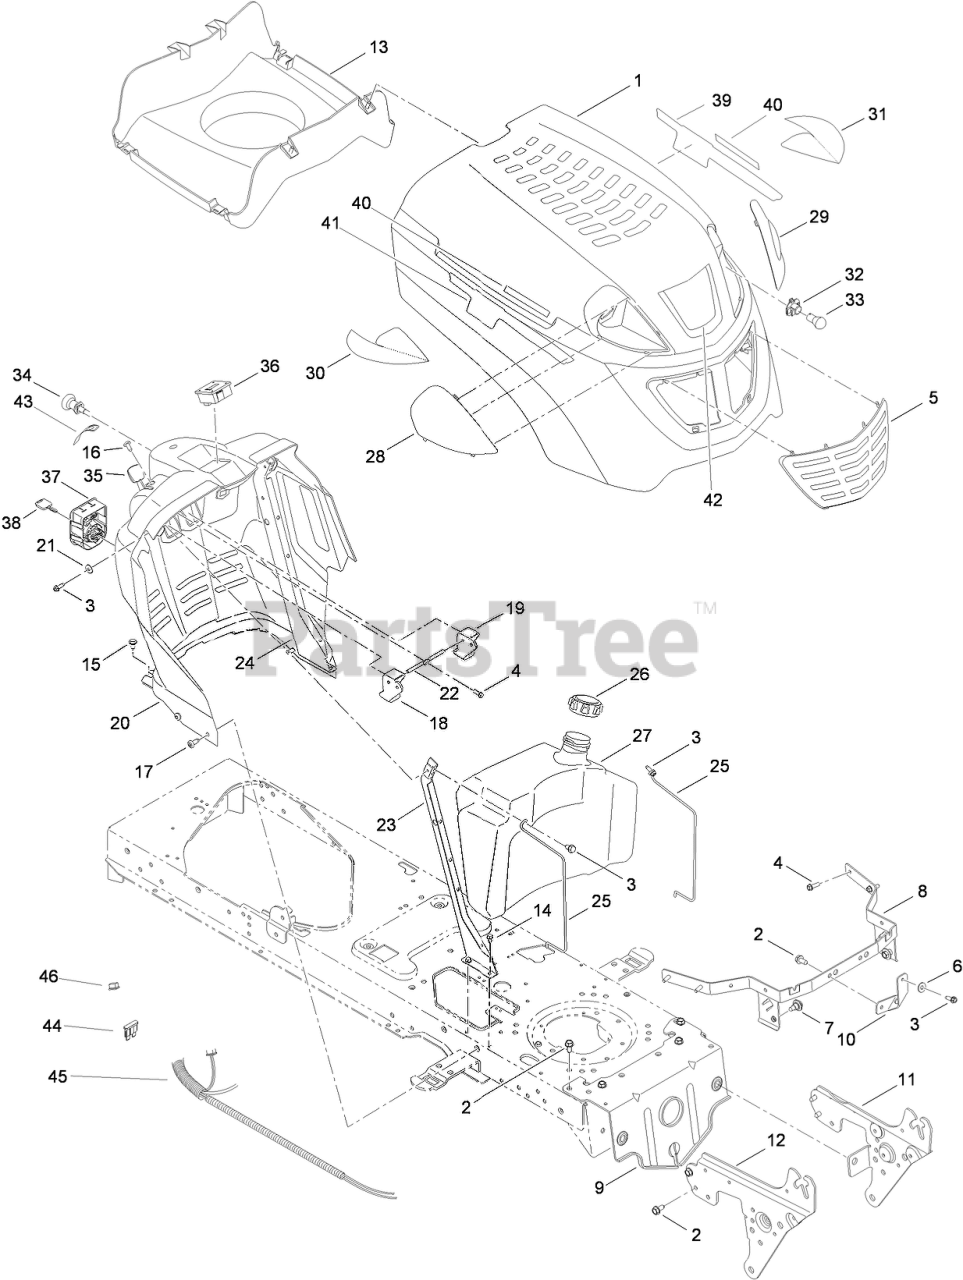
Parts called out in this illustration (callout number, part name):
2	SCREW-TAP
3	SCREW-TAP
4	SCREW-TAP
6	WASHER-FLAT
7	BOLT-SHOULDER, TAP
8	BRACKET-PIVOT
9	BRACKET-PIVOT
10	BRACKET-SUPPORT, HOOD
11	BRACKET-PIVOT, SUPPORT (LH)
12	BRACKET-PIVOT, SUPPORT (RH)
13	PLENUM-HOOD
14	SCREW-HWHTF
15	SCREW-TAP
16	SCREW-TAP
17	SCREW-TAP
18	LEVER-CRUISE
19	LEVER-BRAKE
20	DASH-PTO, ELECTRIC
21	WASHER-SPRING
22	ROD-LEVER, BENT
23	SUPPORT-DASH, RH
24	SUPPORT-DASH, LH
25	ROD-SUPPORT
26	CAP-FUEL
27	TANK-FUEL, 3 GAL
28	LENS-RH
29	LENS-LH
30	REFLECTOR-RH
31	REFLECTOR-LH
32	SOCKET-HEADLIGHT
33	LAMP-12V, MINIATURE
34	CABLE CONTROL ASM (W/CHOKE KNOB)
35	CABLE-THROTTLE
36	METER-HOUR
37	MODULE-SWITCH, IGNITION
38	KEY-IGNITION
39	DECAL-HOOD, LEFT SIDE
40	DECAL-SIDE PANEL
41	DECAL-HOOD, RIGHT SIDE
42	DECAL-HOOD
43	DECAL-THROTTLE, DASH
44	FUSE-20 AMP
45	WIRE-HARNESS
